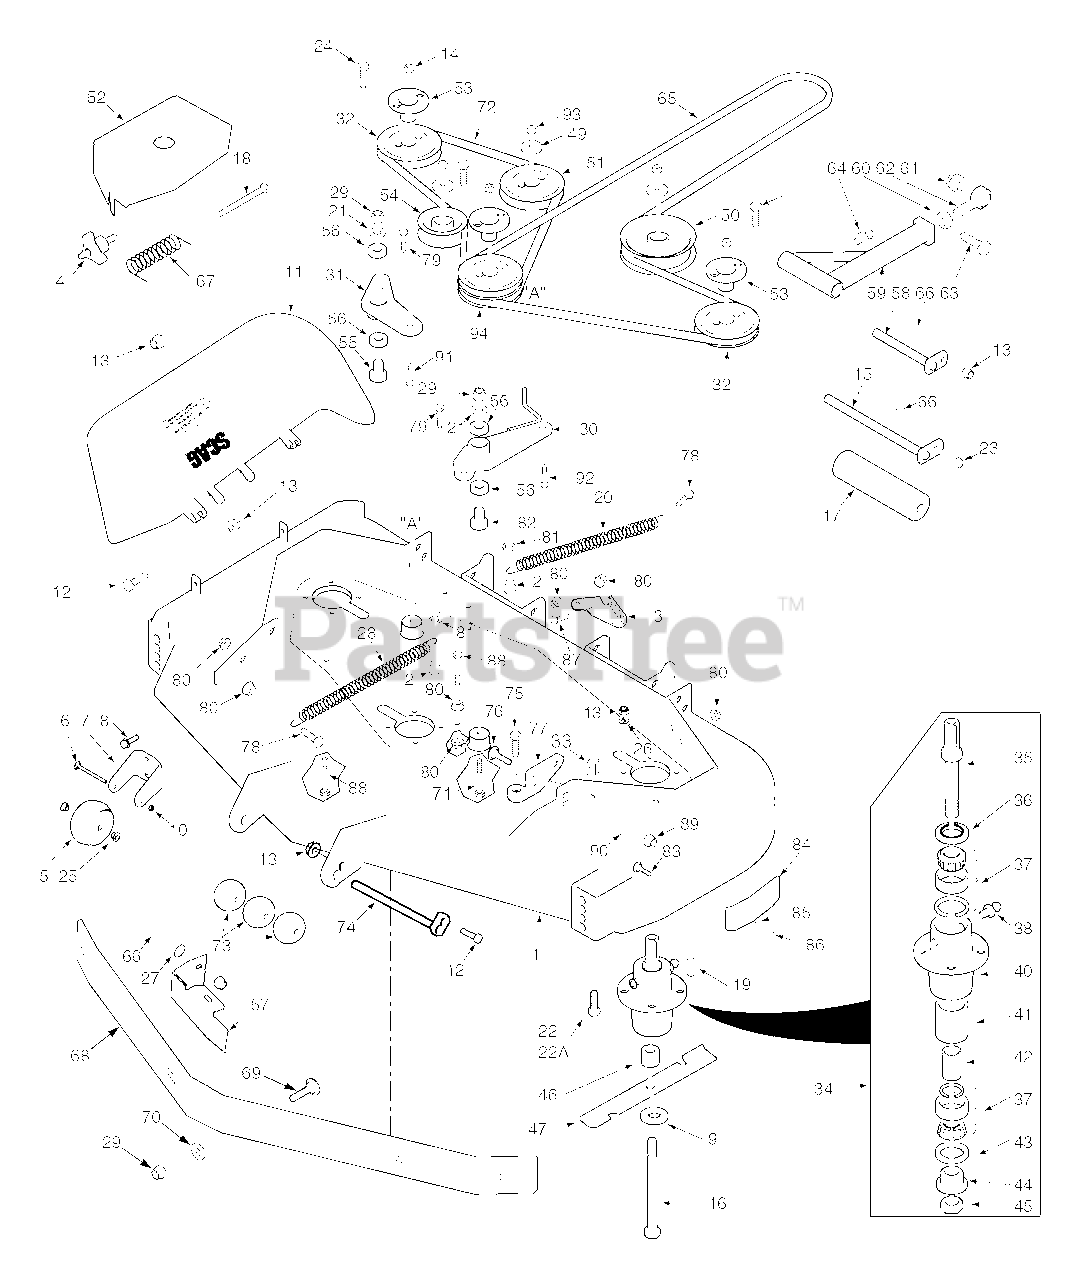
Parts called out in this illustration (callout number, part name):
1	Cutter Deck Velocity Plus
2	Boss, Spring Anchor
3	Bracket, L.H. Spring Anchor 61V
4	Wing Nut, 3/8-16
5	Anti-Scalp Wheel
6	Bolt, Carriage 3/8-16 x 4"
7	Bracket, Anti-Scalp Wheel
8	Bolt, Serrated Flange 3/8-16 x 1"
9	Flatwasher, 5/8" Hardened
10	Locknut, 3/8-16 Center Lock
11	Discharge Chute
12	Bolt, Hex Head 5/16-18 x 1-1/2", Rear
13	Nut, Elastic Stop 5/16-18
14	Nut, 5/8-11 UNC
15	Shaft, Roller
16	Bolt, Hex Head 5/8-11 x 9-1/2"
17	Roller, Rear
18	Bolt, Hex Head 5/16-18 x 4-3/4"
19	Key, 1/4 x 1/4 x 2"
20	Spring, L.H. Deck Drive
21	Flatwasher, 3/8" - .938 x .391 x .105
22	Bolt, Hex Head 5/16-18 x 1-3/4" Grade 8
23	Nut, Serrated Flange 5/16-18
24	Bolt, Hex Head 1/4-20 x 1" Grade 8
25	Bushing, .376 ID Oilite
26	Lockwasher 5/16"
27	Flatwasher 5/16"
28	Spring, R.H. Deck Drive
29	Nut, Elastic Stop 3/8-16
30	Idler Arm Assembly, L.H. Drive
31	ldler Arm Assembly, R.H. Drive
32	Pulley, Tapered Bore 6.33" Dia.
33	U-Nut, 3/8-16
34	Spindle Assembly
35	Shaft, Spindle
36	Seal Upper
37	Bearing Assembly
38	Grease Fitting
39	Valve, Grease Relief
40	Housing, Spindle
41	Spacer, Outside
42	Spacer, Inside
43	Seal, Lower
44	Bushing, Bottom
45	Nut, Special 1-1/16 - 18
46	Spacer, Spindle
47	Cutter Blade 21"
48	Pulley, Double Groove 6.33" Dia.
49	Dust Shield
50	Idler Pulley, 5" Dia.
51	Idler Pulley, 5" Dia.
52	Belt Cover (61V)
53	Hub, Tapered 1-1/8" Bore
54	Idler Pulley, 3-1/2" Dia.
55	Pivot, Idler
56	Bearing
57	Turbo Baffle, Bolt On
58	Push Arm Shaft
59	Push Arm
60	Nut, 5/8-18 UNF
61	Nut, Elastic Stop 5/8-11
62	Rod End, 5/8 Male RH Thread
63	Bolt, Hex Head 5/8-11 x 4-1/2"
64	Grease Fitting, 90 Degree
65	Belt, Deck Drive 61V
66	Bolt, Hex Head 5/16-18 x 1"
67	Spring, Discharge Chute
68	Baffle Weldment, 61V
69	Bolt, Carriage 3/8-16 x 1"
70	Flatwasher, 3/8-.391 x .938 x .105
71	Bolt, Hex Head 3/8-16 X 3-1/2"
72	Belt, Deck Drive R.H.
73	Wheel, Anti Scalp
74	Roller Shaft
75	Bolt, Special
76	Bolt, Carriage 7/16-14 x 1-1/4"
77	Lever Assy., Deck Level
78	Bolt, Hex Head 3/8-16 x 1-1/2" Gr.8
79	Bolt, Hex Head 3/8-16 x 1"
80	Nut, Serrated Flange 3/8-16
81	Lockwasher, 5/16"
82	Pivot, Idler Short
83	Bolt, Carr. 5/16-18 x 3/4"
84	Wear Pad
85	Flatwasher, 5/16-.344 x .688 x .065
86	Nut, Center Lock 5/16"
87	Bolt, Hex Head 3/8-16 x 1"
88	Bolt, Hex Head 3/8-16 x 2-1/2"
89	Nut, Elastic Stop 7/16-14
90	Flatwasher, 7/16-.500 x 1.250 x .083
91	Bolt, Hex Head 3/8-16 x 2-1/4"
92	Bolt, Hex Head 3/8-16 x 3"
93	Nut, Elastic Stop 3/8-16
94	Pulley, Double Groove 6.33 Dia.
